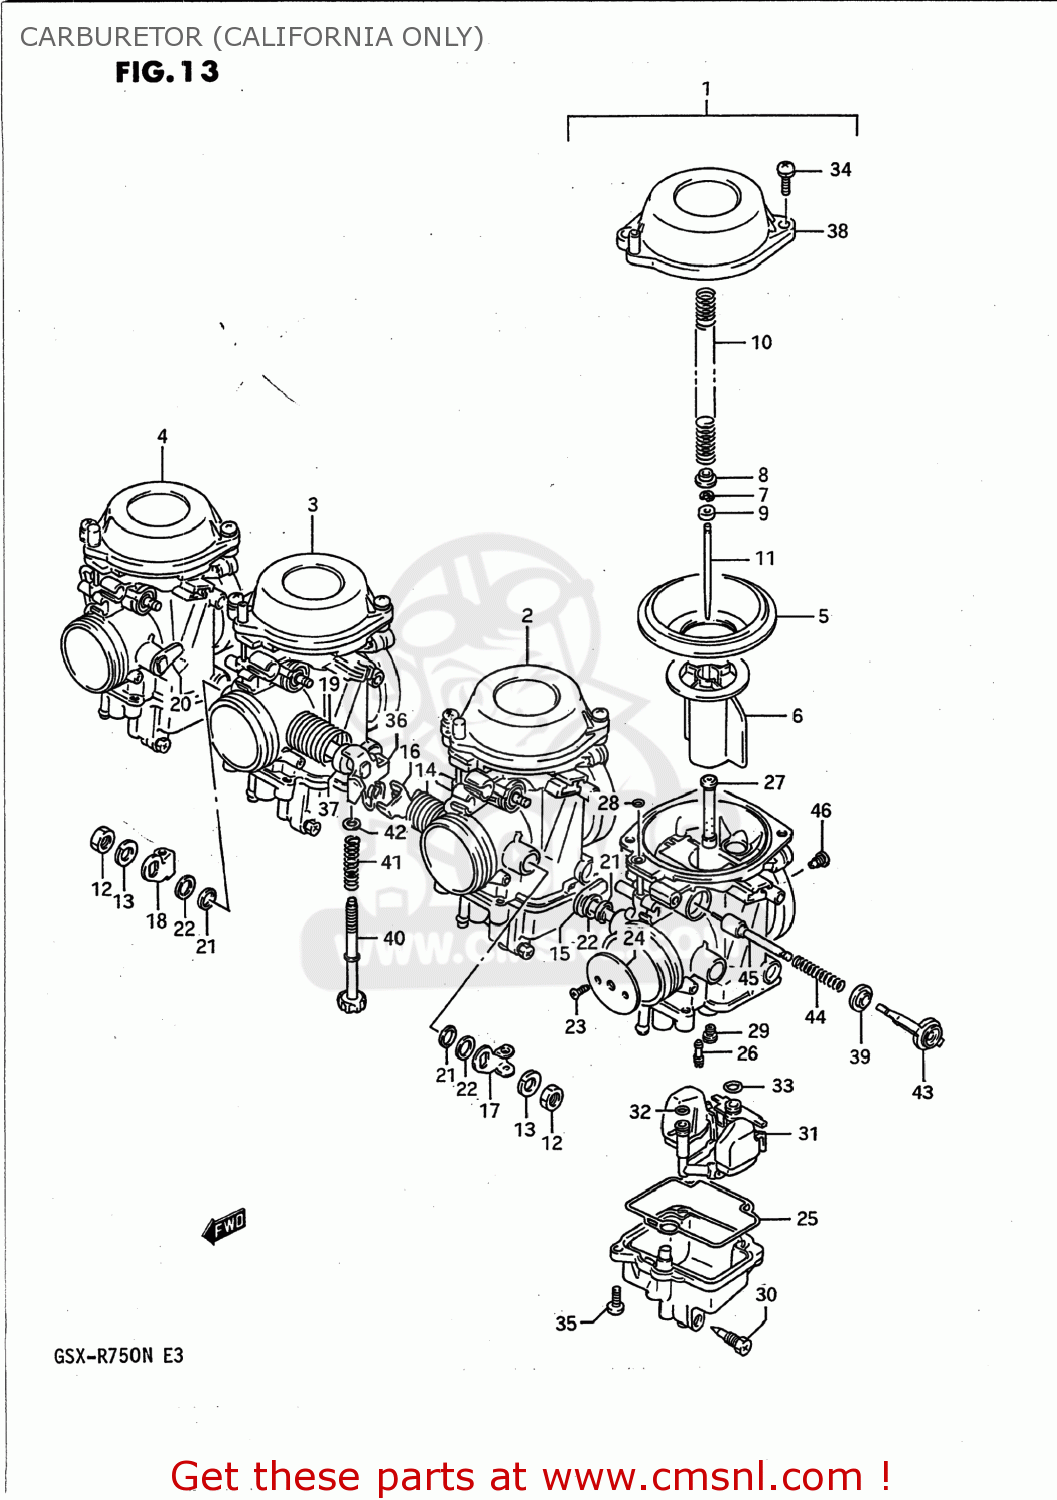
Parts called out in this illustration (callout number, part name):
1	CARBURETOR ASSEMBLY,LEFT
2	CARBURETOR ASSEMBLY,MIDDLE,LEFT
3	CARBURETOR ASSEMBLY,MIDDLE,RIGHT
4	CARBURETOR ASSEMBLY,RIGHT
5	DIAPHRAGM
6	VALVE,PISTON
7	CLIP,NEEDLE
8	RING
9	RING
10	SPRING
11	NEEDLE,JET
12	NUT
13	WASHER,LOCK,8.
14	SPRING
15	SHAFT ASSEMBLY
16	SHAFT ASSEMBLY
17	LEVER
18	LEVER,THROTTLE
19	SPRING
20	SHAFT ASSEMBLY
21	SEAL
22	GASKET,THROTTLE SHAFT (NAS)
23	SCREW
24	VALVE,THROTTLE
25	GASKET,FLOAT CHAMBER (NAS)
26	JET,PILOT(32.5)
27	JET,NEEDLE(Y-5)
28	O RING
29	JET,MAIN(112.5)
30	SCREW
31	FLOAT/NEEDLE VALVE ASSY
32	O RING
33	O-RING,NEEDLE VALVE
34	SCREW
35	SCREW
36	SHAFT ASSEMBLY
37	RING
38	COVER,DIAPHRAGM
39	CAP,STARTER
40	SCREW
41	SPRING
42	WASHER
43	HOLDER,GUIDE
44	SPRING
45	PLUNGER ASSY
46	JET,AIR(1.3)
